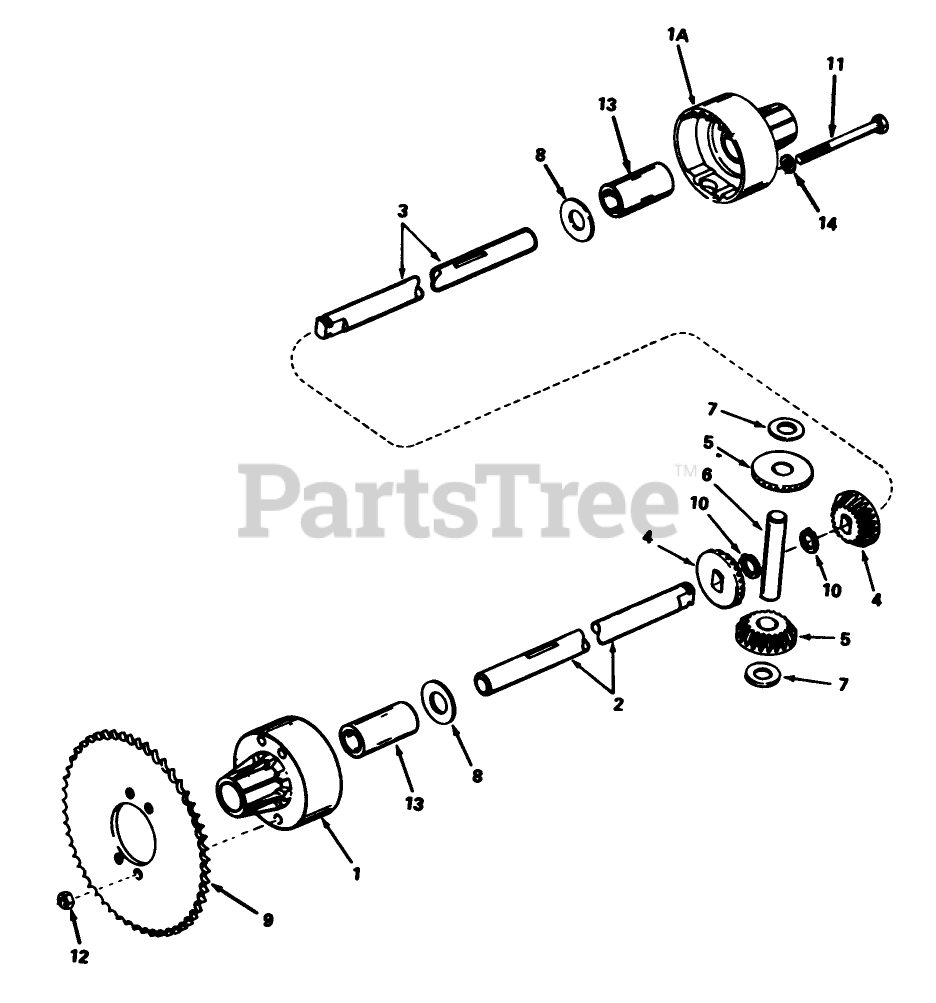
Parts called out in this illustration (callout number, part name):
1	Housing, Differential Carrier (Incl. Ref. #13)
1A	Housing, Differential Carrier (Incl. Ref. #13)
2	Axle (9-5/8" long)
3	Axle (18-1/4" long)
4	Bevel Gear
5	Gear Pinion
6	Pin Drive
7	Washer Thrust
8	Washer
10	Ring-Snap
11	Screw-Hex Hd.
12	Nut-Lock
13	Bushing
14	Washer
